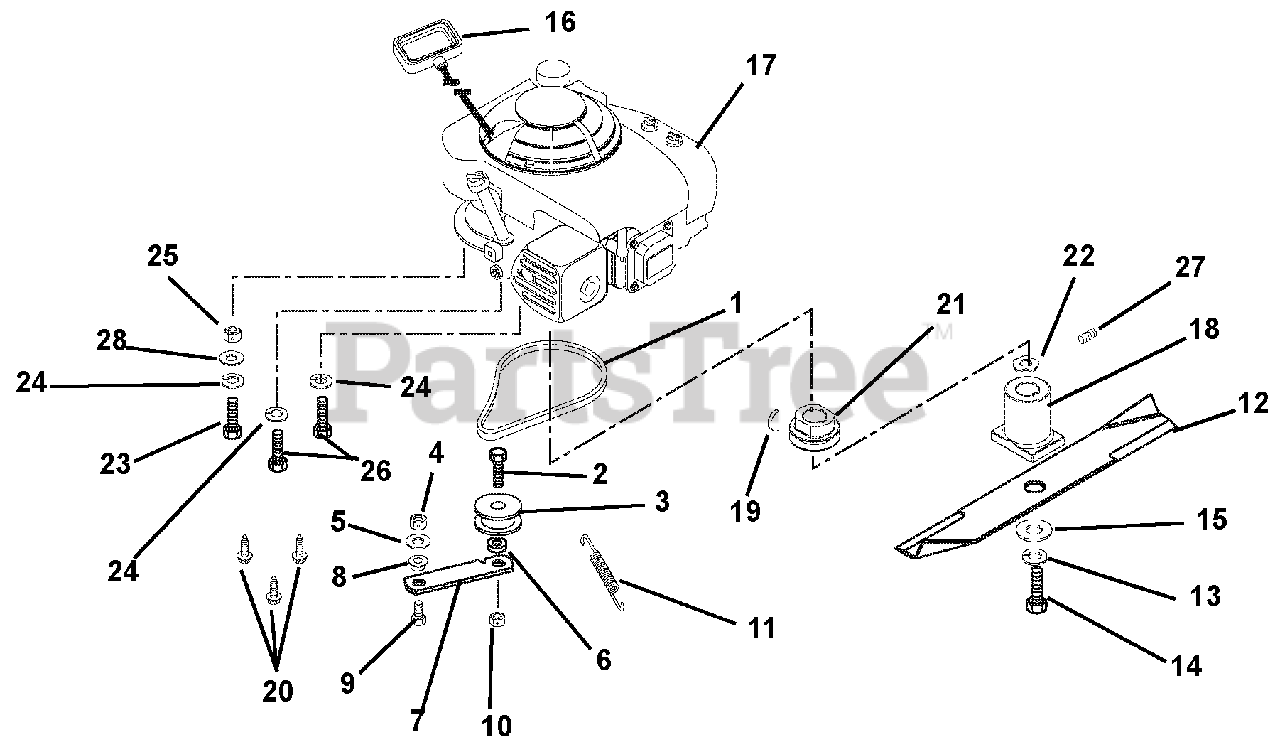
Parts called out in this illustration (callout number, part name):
1	V-BELT, 3L-COGGED
2	@BLT-HEX .44-14X1.50 GR5 YWZC
3	IDLER-FLAT 1.75 X .47
4	@NUT-LK-CTR .31-18 YWZC
5	@WSHR-FL-STL.344X.688X.065YWZC
6	BSHG-SLV .469 X .750 X .430
7	IDLER ARM
8	BSHG-FLG .325X.501X.250X1.120
9	@BLT-HEX .31-18X.75 GR5 YWZC
10	@NUT-LK-CTR .44-14 YWZC
11	SG-TENS .043X.44X3.31 WLD 5.8
12	BLADE, 21" LM MULCHING
12	21" MOWER BLADE
12	BLADE, 21" MOWER TUNGSTEN
13	@WSHR-LK .38X.094 REG YWZC
14	BLT-HEX .38-24 X 2.00 GR8 YWZC
15	WSHR-FL-STL .390X1.5X.125 YWZC
16	HANDLE, RECOIL START
17	ENGINE, B&S QUANTUM 6.5HP
17	ENG, B&S 6.75HP INTEK OHV RCL
17	ENGINE - HONDA 5.5 HP OHV
17	ENGINE, KAWASAKI 6.0 CONSUMER
18	ADAPTER-SINTERED IRON LM
18	ADAPTER - BLADE HUB
19	KEY-WDRF .156X.625X.25 SAE 6
20	@SCR-TAP .38-16X1.00 HWH TR YZ
21	PULLEY-SINTERED IRON LM
21	PULLEY - UNV DRIVE - STEEL
22	WASHER-WAVE .885X1.311X.125
23	BLT-HEX .31-24X1.50 GR5 YWZC
24	@WSHR-LK .31X.078 REG YWZC
25	NUT-HEX .312-24 YWZC
26	BLT-HEX .31-24X1.00 GR5 YWZC
27	SCR-SET .31-18X.38 SKHCUPDL
28	@WSHR-FL-STL.344X.688X.065YWZC
